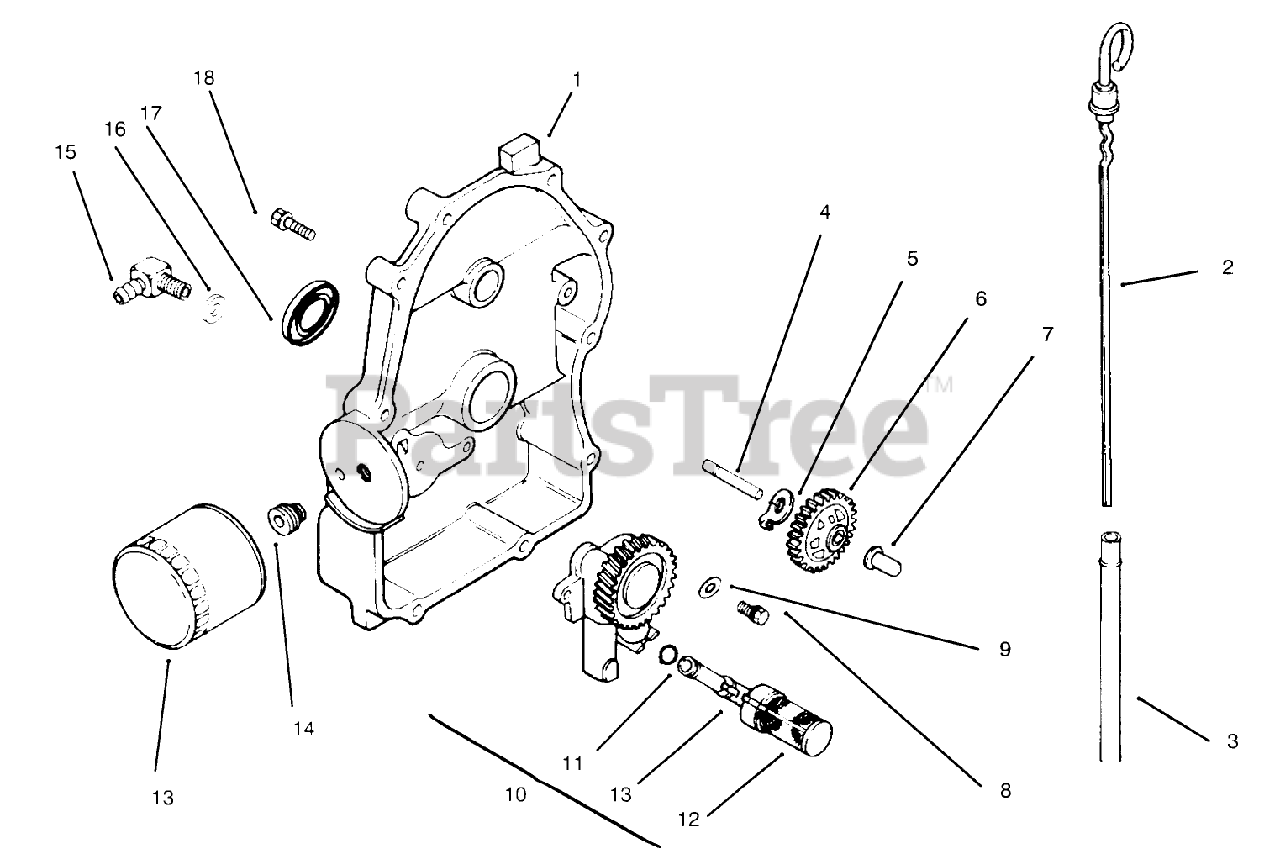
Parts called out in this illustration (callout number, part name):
1	Plate-Closure (Incl. Ref.#2-7, 10-12, 16 & 17)
2	Dipstick
3	Tube-Dipstick
4	Shaft-Gear, Governor
5	Tab-Locking
6	Kit-Governor Gear Asm (Incl. Ref. #7)
7	Pin-Governor
8	Screw
9	Washer
10	Oil Pump Assembly (Incl. Ref. #11-12)
11	O-Ring
12	Pick-up,Oil
13	Filter-Oil
14	Nipple-Filter, Oil
15	Connector
16	O Ring
17	Seal-Oil
18	Screw
